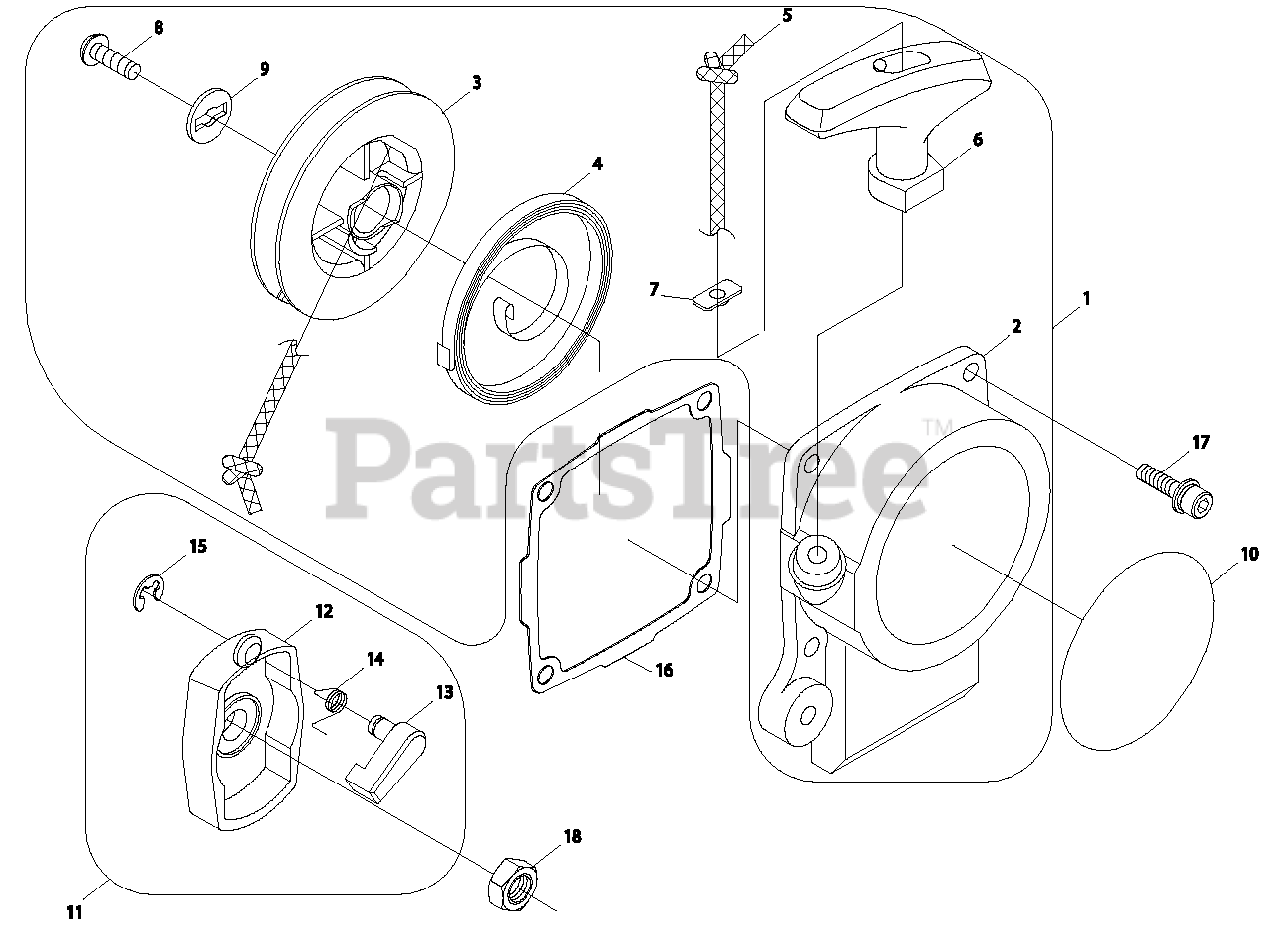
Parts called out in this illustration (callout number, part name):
1	STARTER ASSY
2	CASE, STARTER
3	REEL, ROPE
4	SPRING, REWIND
5	ROPE, STARTER
6	GRIP, STARTER
7	RETAINER, ROPE
8	SCREW - 5
9	WASHER
10	LABEL - MODEL
11	STARTER PAWL ASSY
12	REEL, ROPE
13	PAWL, STARTER
14	SPRING, RETURN
15	RING, RETAINING
16	GASKET, STARTER
17	SCREW - 5X25
18	NUT
